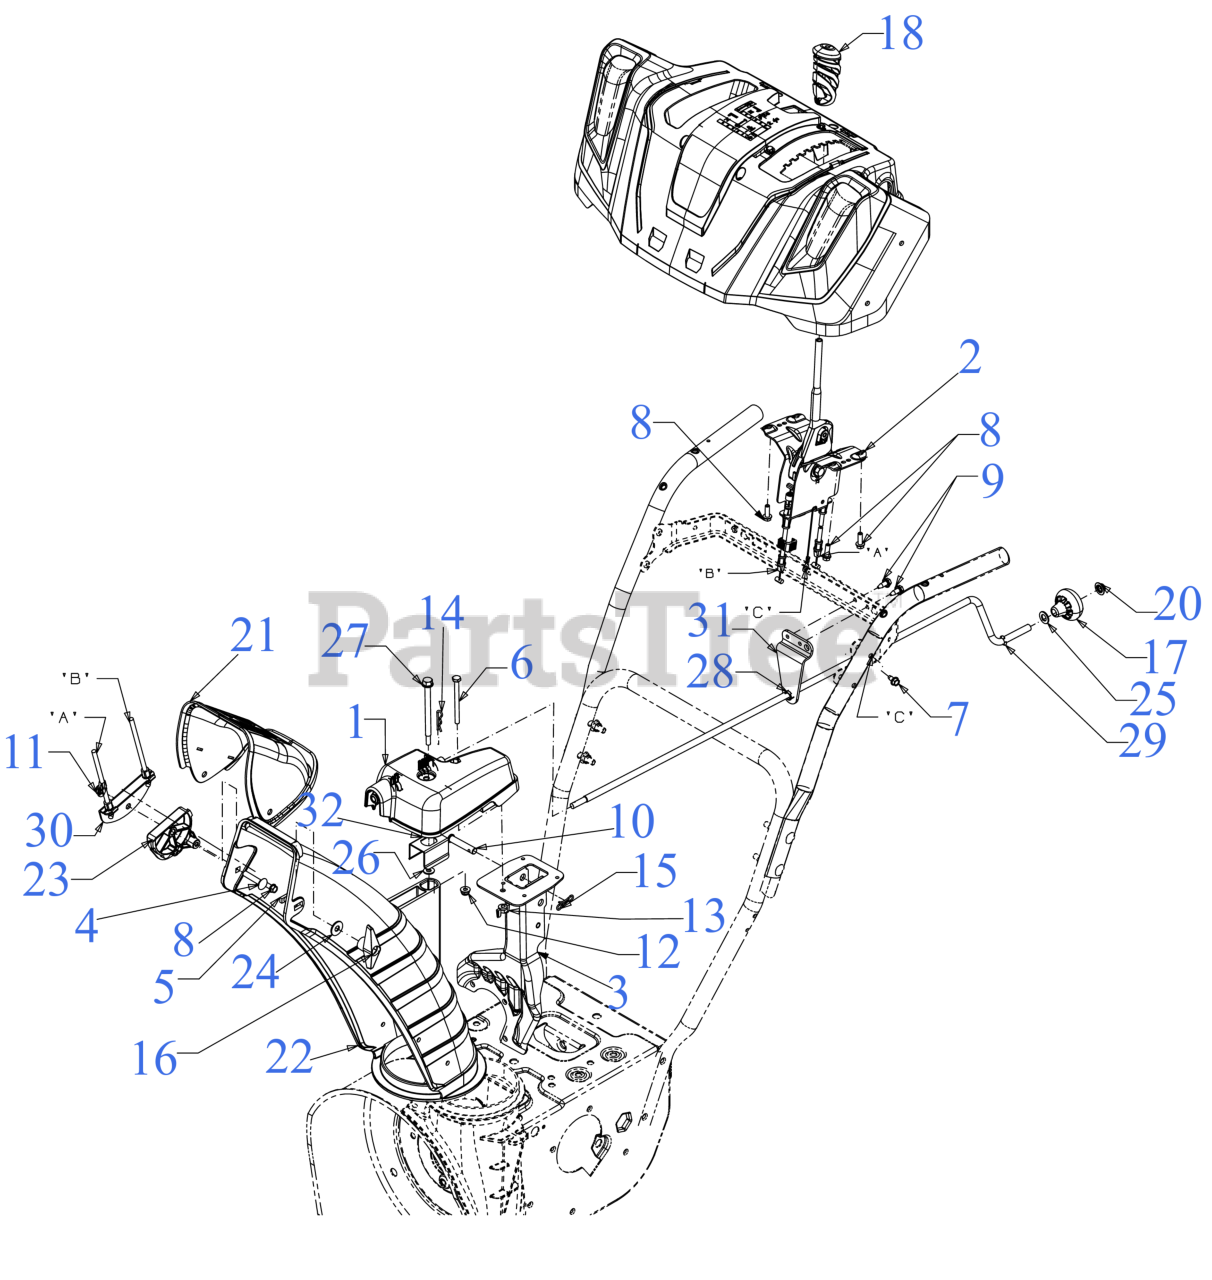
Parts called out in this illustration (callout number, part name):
1	2-WAY CHUTE ROTATE GEARBOX
2	2-WAY CHUTE CONTROL ASSEMBLY
3	CHUTE SUPPORT ASSEMBLY
4	CARRIAGE BOLT 5/16-18 x 1.50
5	CARRIAGE BOLT 5/16-18 x 1
6	SCREW 1/4-20 x 3.0 GR5
7	SCREW 1/4-20 X.500
8	SCREW 1/4-15 x .750
9	SCREW 1/4-20X.625
10	CLEVIS PIN 3/8 x 1.87
11	FLANGE LOCK NUT 5/16-18
12	FLANGE LOCK NUT
13	WING NUT 1/4-20
14	INTERNAL COTTER PIN
15	BOW TIE COTTER PIN 1/4-5/16
16	WING KNOB NUT
17	SHIFT KNOB
18	PTO HANDLE GRIP .355 ID
21	UPPER REMOTE CHUTE WITH LABEL
22	LOWER CHUTE 5"
23	CABLE CHUTE GUIDE
24	FLAT WASHER
25	FLAT WASHER
26	FLAT WASHER
27	SHOULDER SCREW
28	BUSHING .380 ID
29	CHUTE CRANK .375 DIA x 31"
30	CABLE BRACKET
31	ROD SUPPORT BRACKET
32	CHUTE BRACKET
